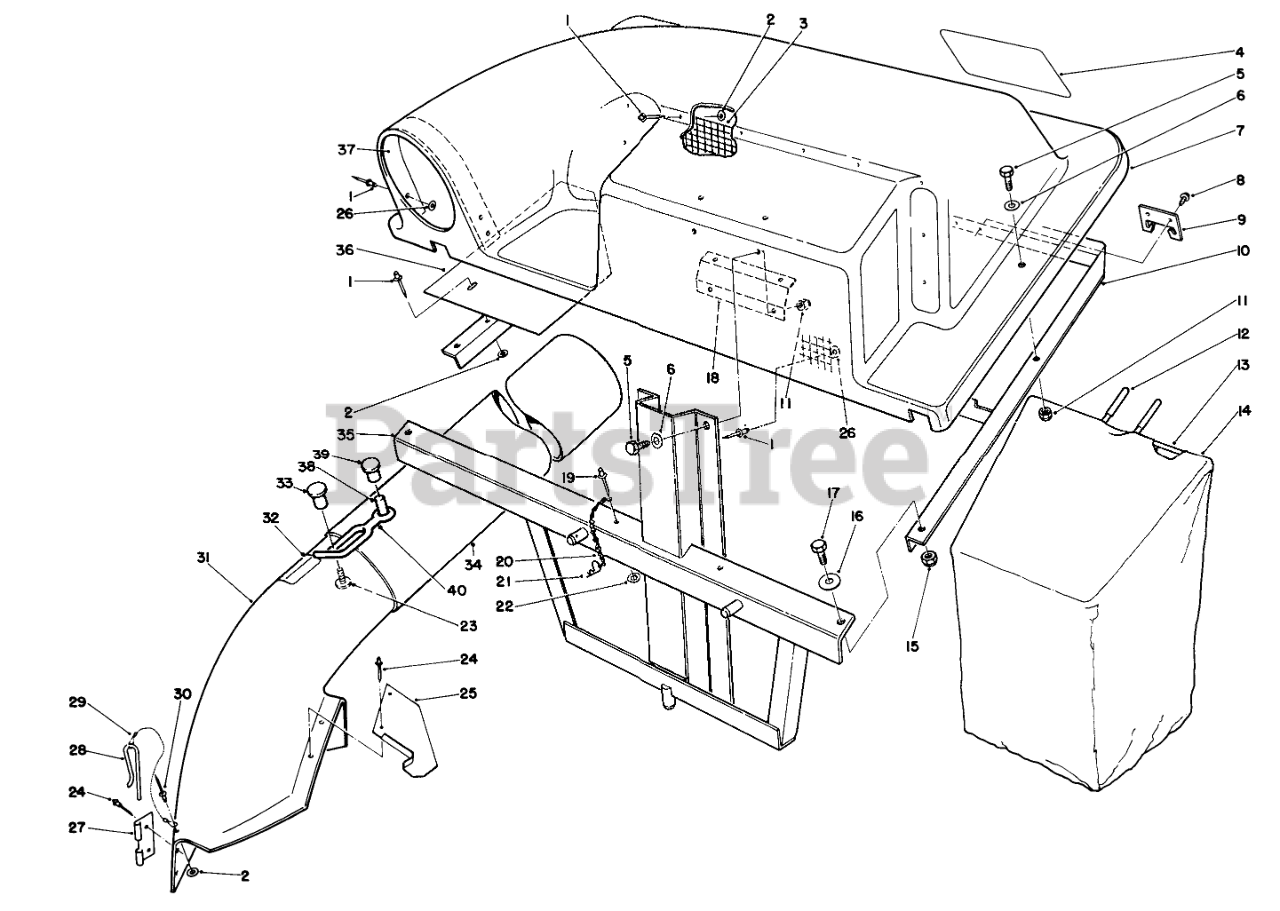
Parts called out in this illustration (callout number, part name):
1	RIVET-POP
2	WASHER-PLAIN
3	SCREEN
4	DECAL-BAGGER, TWIN
5	SCREW-HH
6	WASHER-PLAIN
7	COVER-BAGGER, TWIN
8	SCREW-HWH
9	BRACKET-FRAME, BAG
10	Cover-Frame
11	NUT-LOCK, NI
12	GRIP-HANDLE, BAG
13	Frame-Bag
15	NUT-LOCK, NI
16	WASHER-FLAT
17	SCREW-HH
18	Plate-Backup
20	10 LINK CHAIN W/O HOOK
21	PIN-HAIR
22	WASHER-BACK
23	Screw
24	RIVET-BLIND
25	CHUTE SUPT BRKT
26	WASHER-FLAT
27	BRACKET-MOUNTING, CHUTE
28	PIN-LOCKING, CHUTE
29	LANYARD
30	RIVET-BLIND
31	Assembly-Chute (Incl. Ref. #24-30 & 32)
32	DECAL-DANGER
34	TUBE(ROUND&LONG)
35	Frame-Mounting
36	Baffle
37	Support Inlet
38	SPACER-INTERLOCK
39	FASTENER-PANEL
40	RETAINER-DUCT
